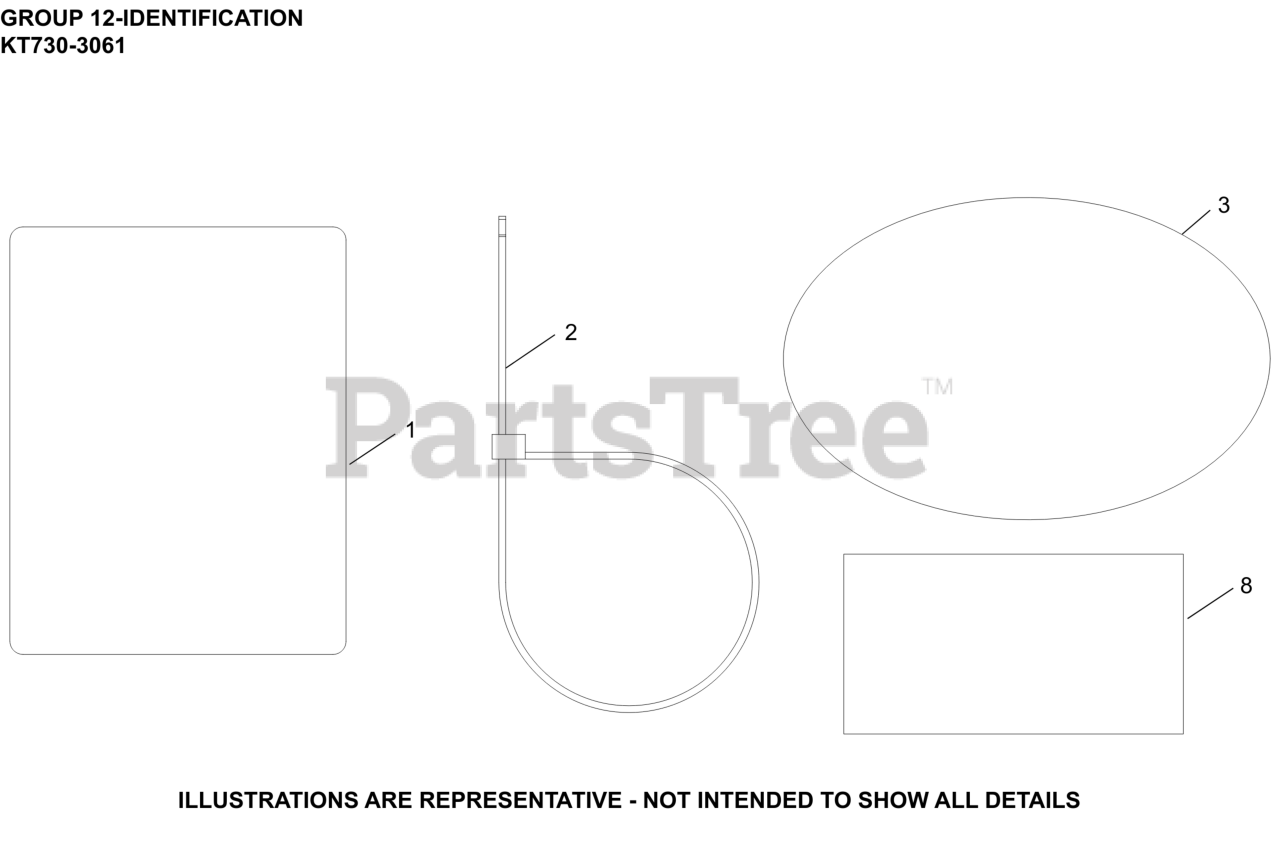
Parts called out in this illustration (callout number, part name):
1	LABEL, CLEAR LAMINATION
3	LABEL, 7000 SERIES (725CC)
8	DECAL, USA
